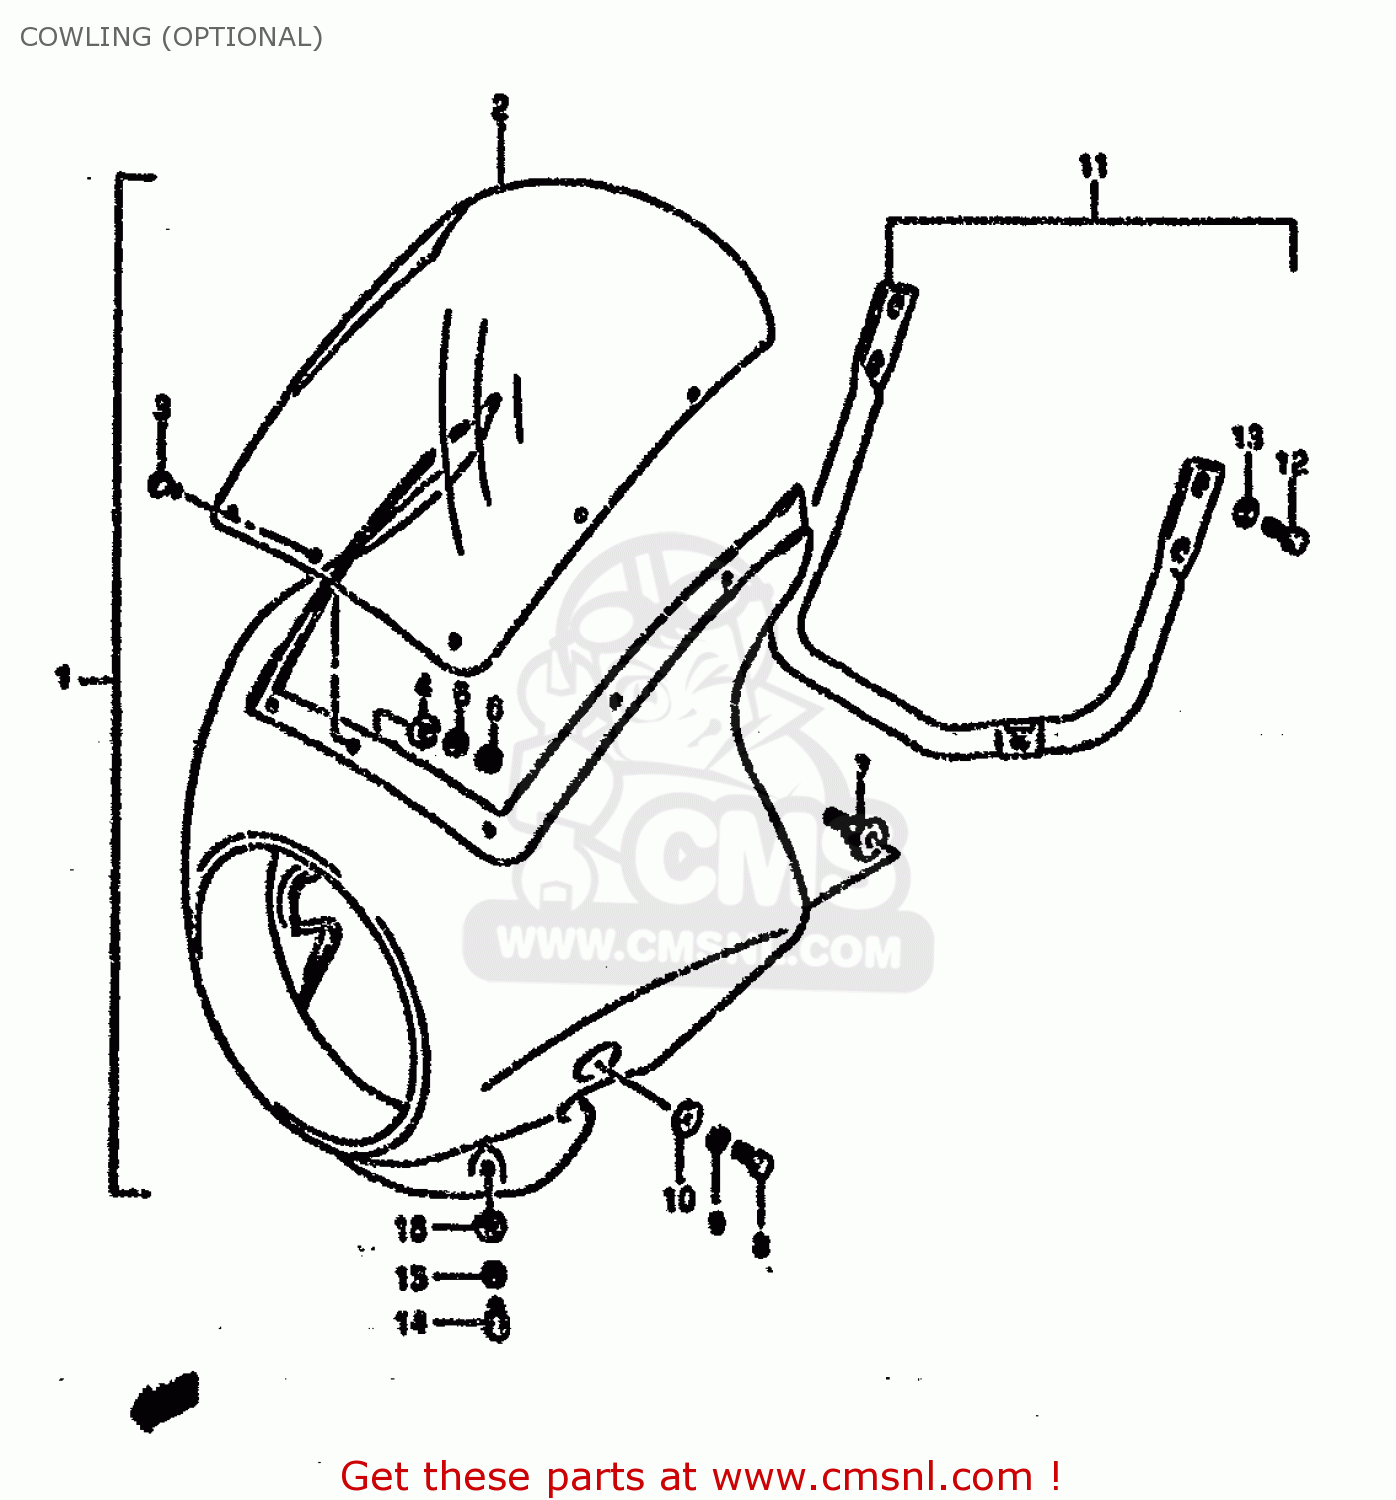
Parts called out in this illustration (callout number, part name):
1	UPPER COWLING SET
2	SCREEN,COWLING
3	SCREW
4	WASHER
5	WASHER,LOCK
6	NUT
7	BOLT,COWLING HEADLAMP
8	BOLT
9	WASHER,LOCK
10	WASHER(6.5X18X1.6)
11	BRACE,UPPER COWLING
12	BOLT
13	WASHER
14	BOLT
15	WASHER,LOCK
16	WASHER
